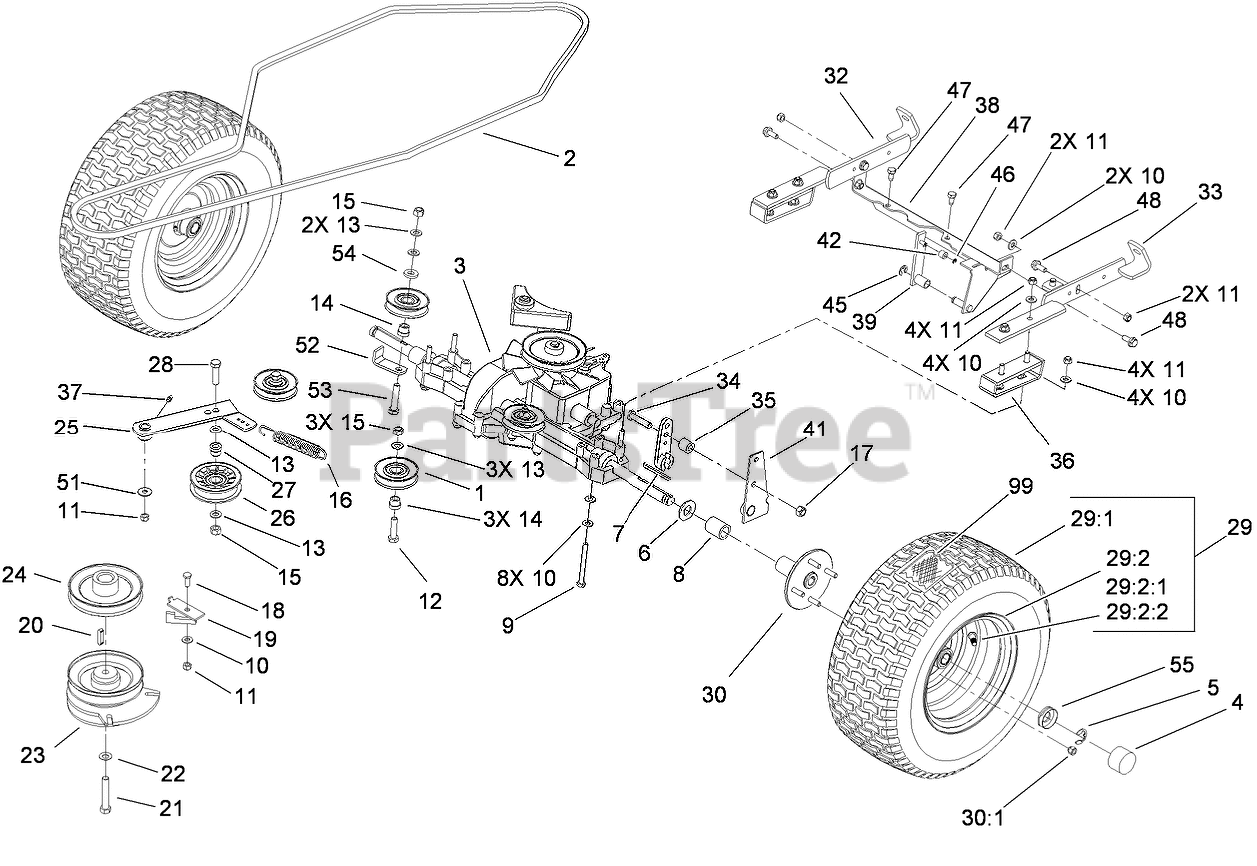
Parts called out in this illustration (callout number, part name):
1	PULLEY-IDLER
2	V-BELT-TRACTION
3	TRANSMISSION
4	CAP-HUB
5	CLIP-SPRING
6	WASHER
7	KEY-SQUARE
8	SPACER-AXLE
9	SCREW-HH
10	WASHER-PLAIN
11	NUT-LOCK, NI
12	SCREW-HH
13	WASHER-FLAT
14	BUSHING-IDLER
15	NUT-LOCK, NI
16	SPRING
17	NUT-LOCK, NI
18	SCREW-HH
19	RETAINER
20	KEY-SQUARE
21	SCREW-HH
22	WASHER-SPRING, BELLEVILLE
23	CLUTCH-ELECTRIC
24	PULLEY-ENGINE
25	ARM-IDLER
26	PULLEY-IDLER
27	BUSHING-IDLER
28	SCREW-HH
29	Tire and Wheel ASM
29:2	WHEEL ASM
29:2:1	Rim
29:2:2	Valve-Tire
30	HUB-WHEEL
30:1	NUT-LUG
32	Bracket-Right
33	Bracket-Left
34	SCREW-HH
35	SLEEVE
36	Plate-Reinforcing
37	FITTING-GREASE
38	Bar ASM
39	Arm-Switch
42	Roller
45	Stirrup
46	STIRRUP
47	SCREW-THREAD FORMING
48	SCREW-HEX
51	WASHER-PLAIN
52	RETAINER-BELT
53	SCREW-HH
54	WASHER-FLAT
55	RETAINER-CAP, HUB
